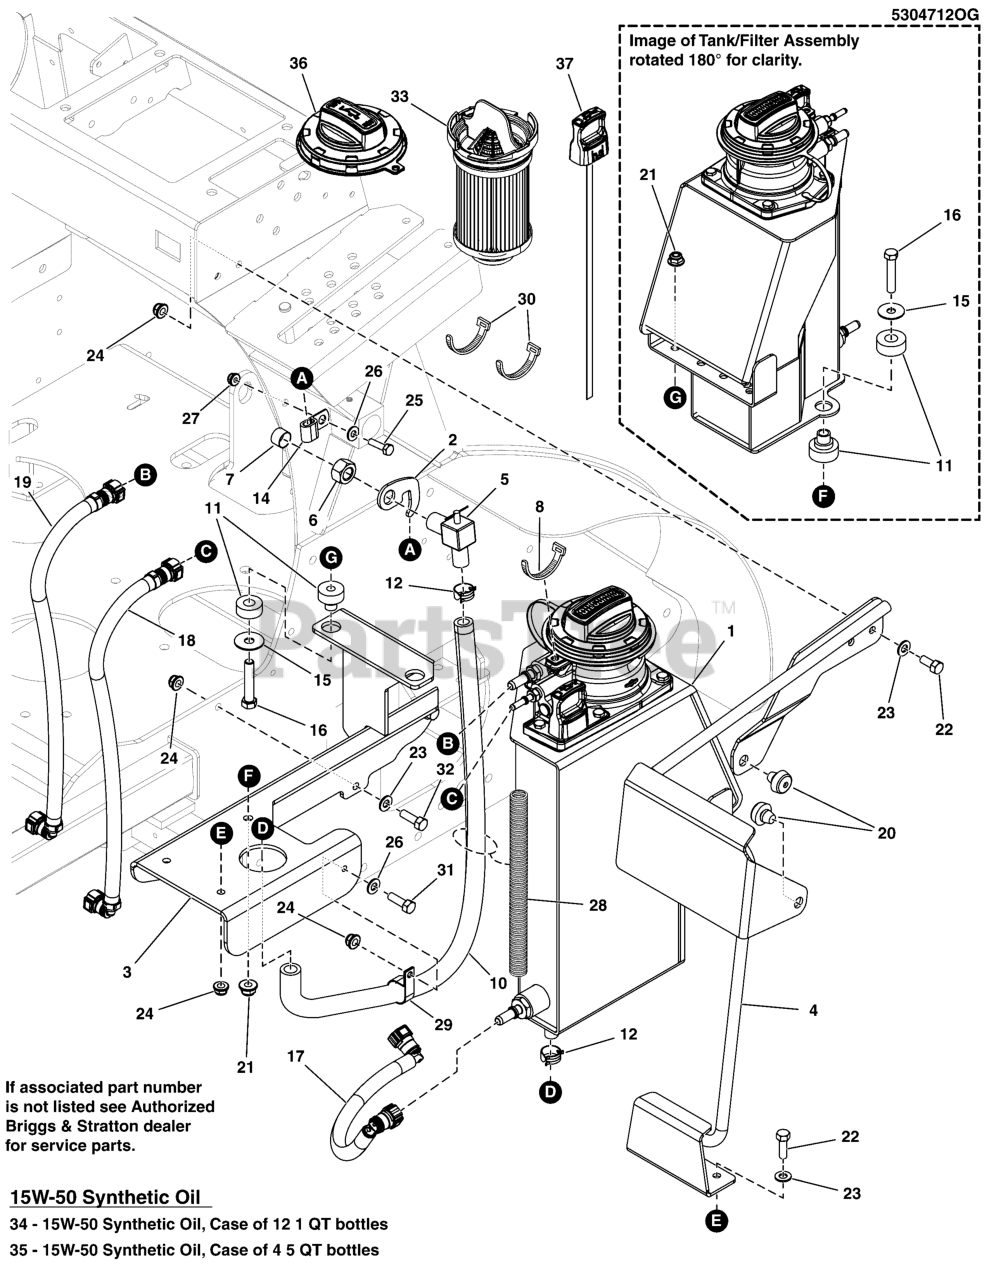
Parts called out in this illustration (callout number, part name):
1	TANK, Oil
1	TANK, OIL
2	PLATE, DRAIN HOOK, OG - BLK
3	WELD, TANK MOUNT, Z2 OG - BLK
4	WELD, TANK GUARD, Z2 - BLK
5	VALVE, OIL DRAIN, M16X1.5 TO 1/2"
6	NUT, HEX, M16-1.5, DAPCO 4071
7	OIL DRAIN CAP, OIL GUARD, DAPCO 4692
10	HOSE, Formed, Oil Guard
11	MOUNT, ISO, BOTTOM, RAD 5000Z-DIESEL
12	CLAMP, #6 HOSE, STAINLESS
14	CLAMP, 5/16", DOUBLE, WIRE & TUBE
15	WASHER, 3/8" Fender
16	BOLT, 3/8-16 X 1-3/4" GD5 CZ
17	HOSE, OIL SUPPLY
18	HOSE, Oil Vent
19	HOSE, OIL SCAVENGE
20	MNT, VBRTN, RBBR
21	NUT, 3/8 - 16 HEX NYLOCK FLANGE
22	BOLT, 5/16-18 X 3/4 GD5
23	WASHER, 5/16" SAE
24	NUT, 5/16-18 HEX NYLOCK FLANGE NUT
25	HHCS, 1/4-20 X 0.625, GR5, ZINC/CLEAR
26	WASHER, 1/4 SAE
27	NUT, 1/4-20 Hex Nylock Flange
28	LOOM, CONVOLUTED SPLIT, 1" ID - 16" LONG
29	CLAMP, VINYL INSULATED, 1.00
30	TIE, SELF-LOCKING, 6"
31	BOLT, 1/4"-20 X 3/4" GD5 YZ
32	BOLT, 5/16-18 X 1" GRD5 YZ
33	FILTER, OIL
34	OIL, 15W-50, SYNTHETIC, CASE X 12- 1QT
35	OIL, 15W-50, SYNTHETIC, CASE X 4- 5QT
36	CAP, Oil Fill
37	DIPSTICK
